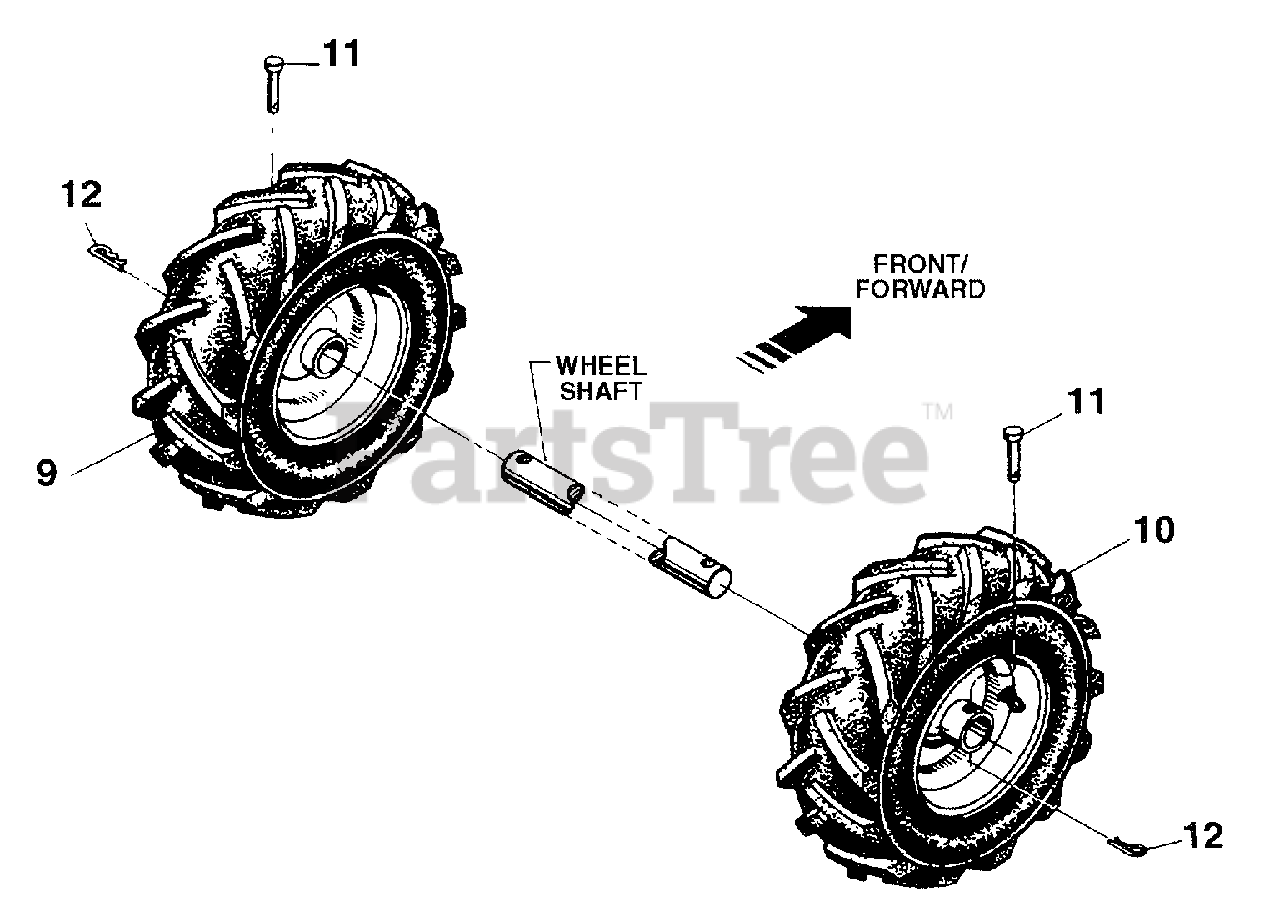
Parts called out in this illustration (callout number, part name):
9	Wheel & Tire Assy-left side
10	Wheel & Tire Assy-right side
11	Clevis Pin-.312 x 1-3/4 long
12	Hitch Pin
